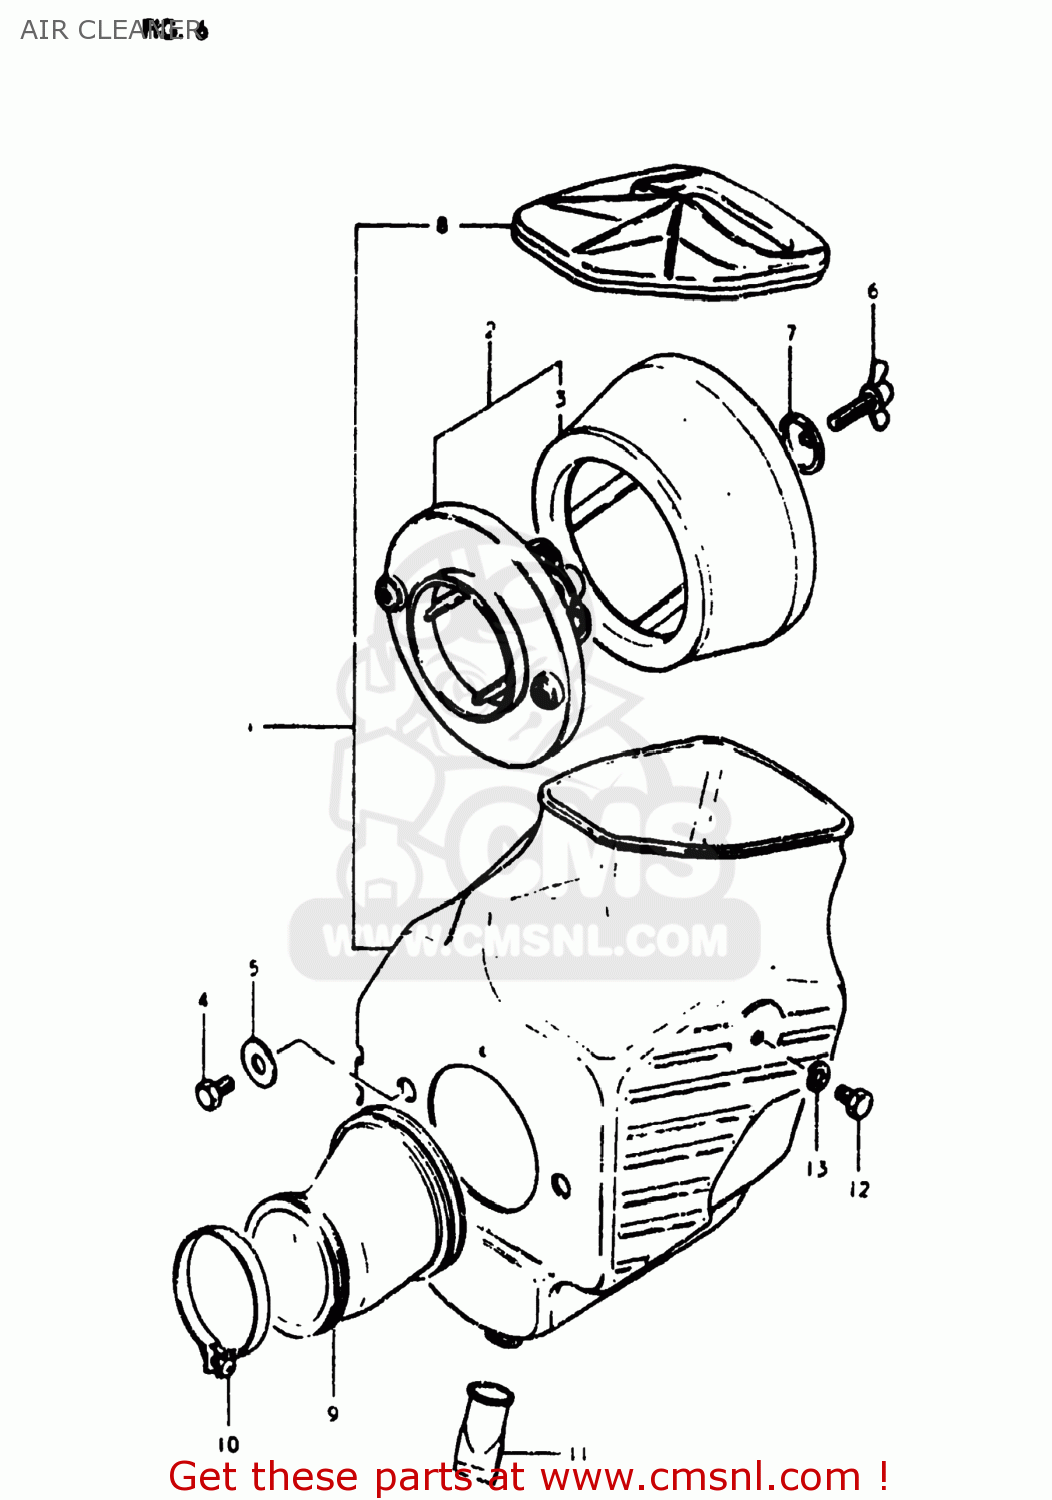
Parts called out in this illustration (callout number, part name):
1	CLEANER ASSEMBLY,AIR
2	FILTER,AIR CLEANER
3	FILTER
4	BOLT
5	SPACER,AIR CLEANER,REAR
6	WING BOLT,AIR CLEANER
7	HOLDER,FILTER
8	CAP,AIR CLEANER
9	TUBE,AIR CLEANER OUTLET
10	CLAMP
11	HOSE,AIR CLEANER DRAIN
12	BOLT
13	LOCK WASHER
